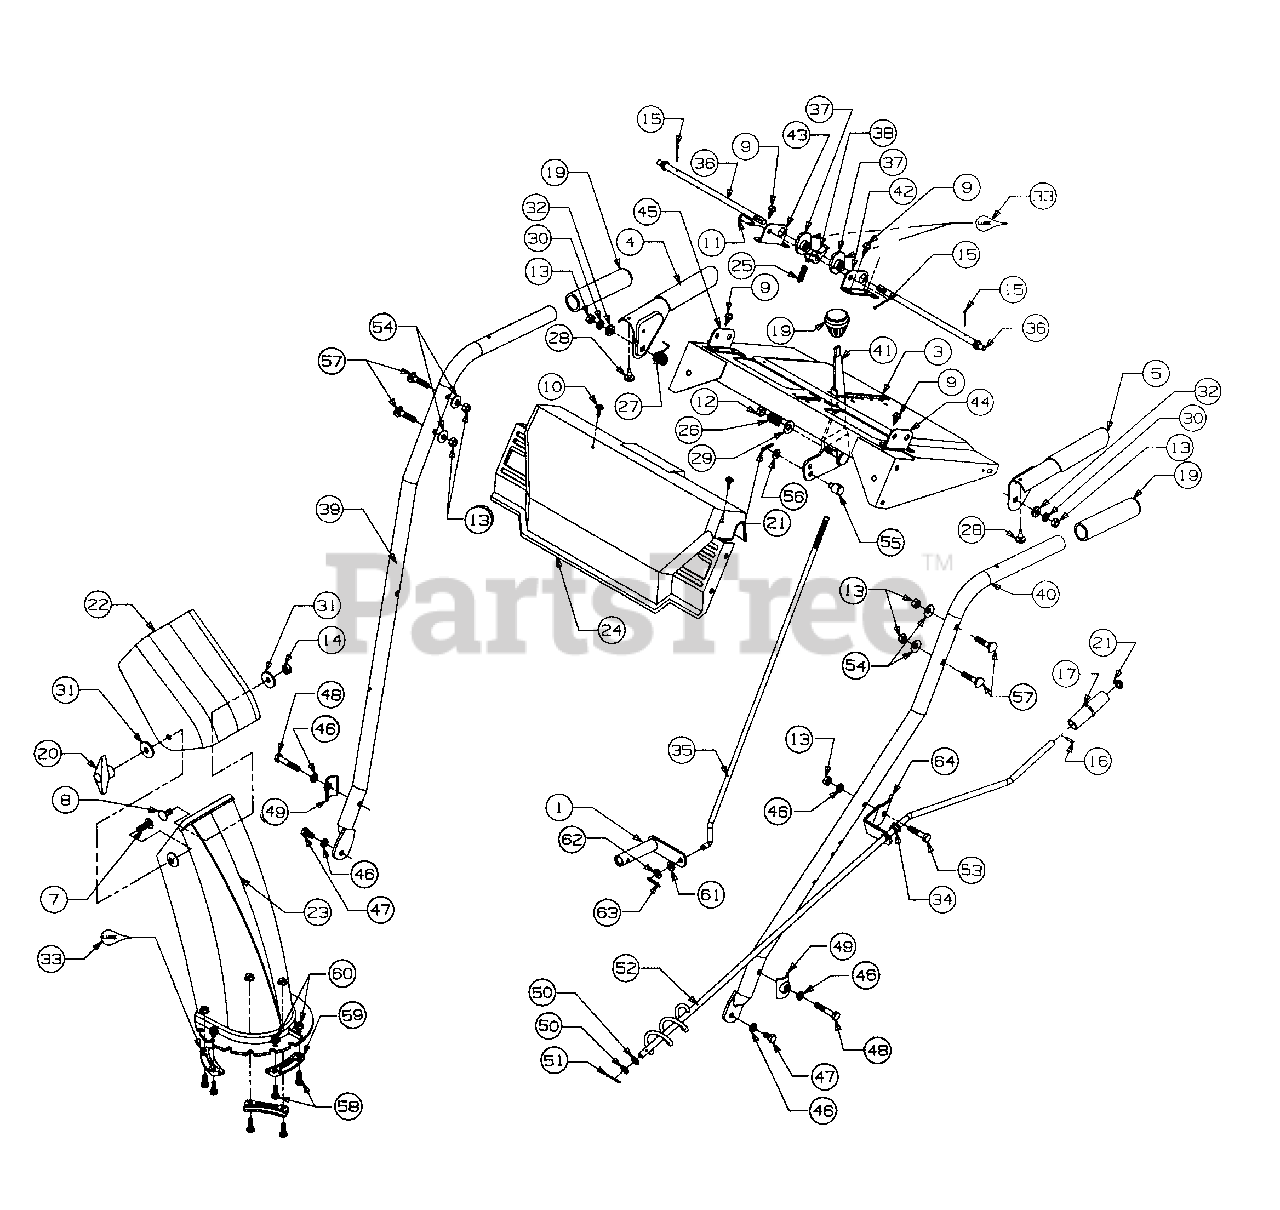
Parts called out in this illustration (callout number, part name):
5	Handle-Engagement - L.H.
7	Screw
8	Bolt-Carriage
9	Screw
10	Screw
11	Pin-Clevis
12	Nut-Hex
13	Nut-Hex
14	Nut-Lock
15	Pin-Cotter
16	Pin-Roll
21	Cap-Push
22	Chute-Upper
23	Chute-Lower
24	Panel-Handle
25	Spring
26	Spring
27	Spring
28	Bumper
29	Washer-Bell
30	Washer-Lock
31	Washer
32	Washer
33	Lubricant
34	Bushing-Plastic
35	Rod-Shift
36	Rod-Cam
37	Cam-Handle Lock
38	Pawl-Handle Lock
46	Washer-Lock
47	Screw
48	Screw
49	Tab-Handle
50	Washer-Flat
51	Pin-Cotter
52	Crank-Chute
53	Screw
54	Washer-Bell
55	Ferrule
56	Washer-Flat
57	Bolt-Carriage
58	Screw
59	Keeper-Chute Flange
60	Nut-Lock
61	Washer-Spring
62	Washer-Flat
63	Pin-Cotter
